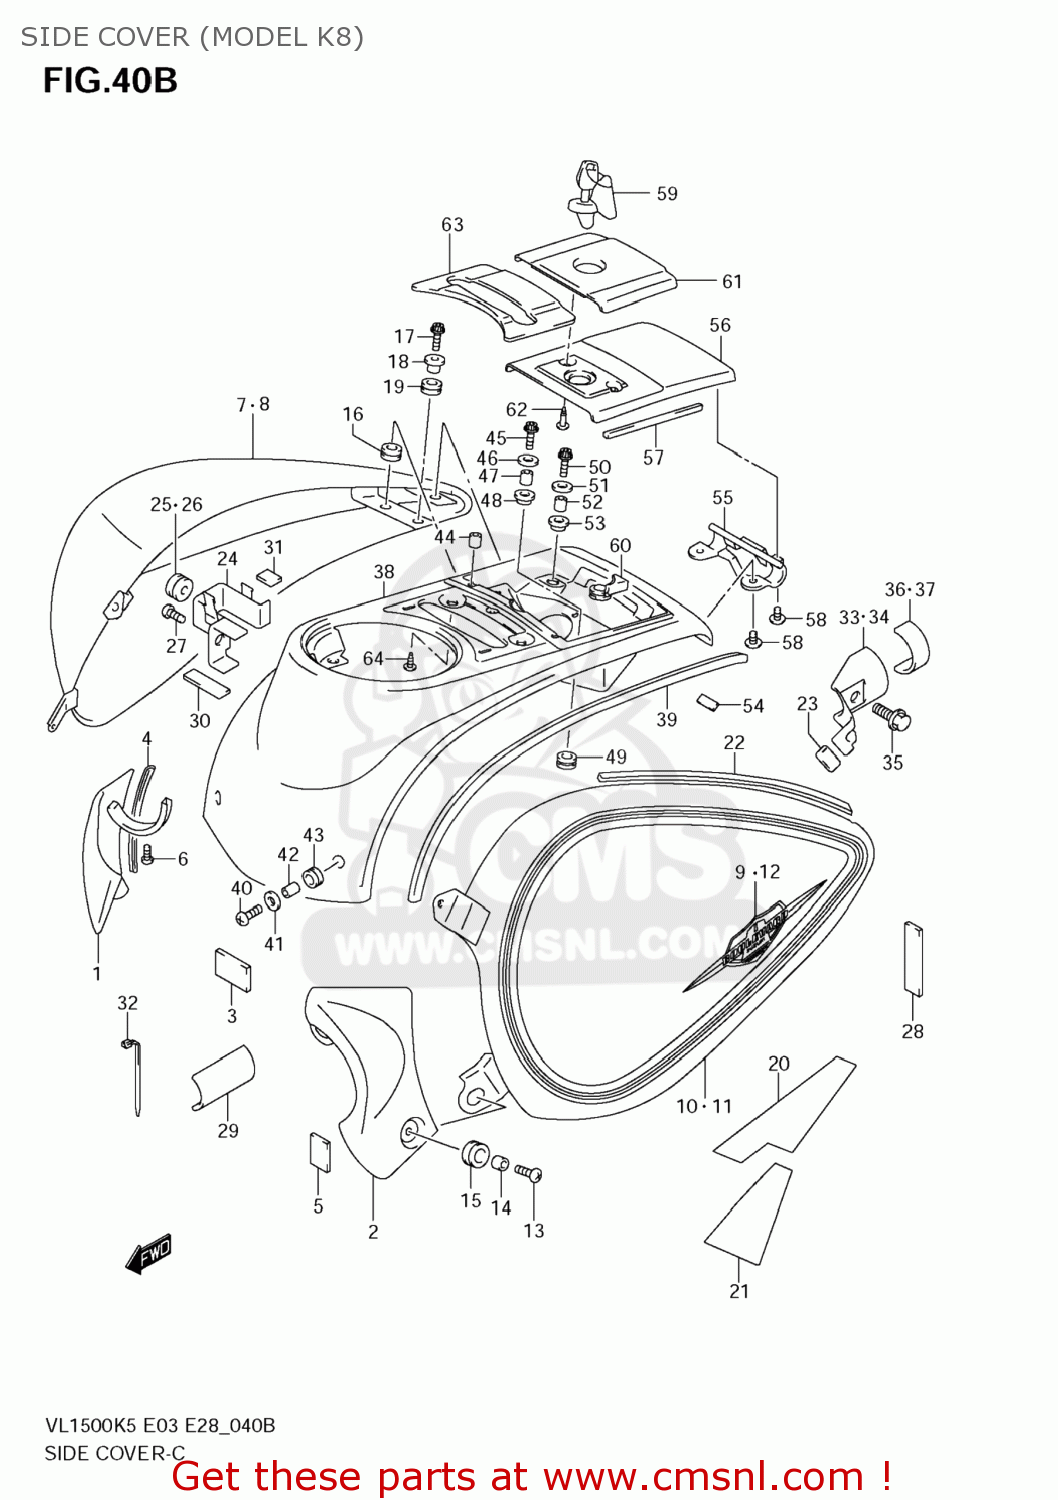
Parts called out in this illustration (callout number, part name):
1	COVER,FRAME HEAD,R
2	COVER,FRAME HEAD,L
3	CUSHION,METER COVER RE
4	MOLDING,FRAME HEAD COVER
5	PROTECTOR,FRAME COVER
6	SCREW(6X20)
7	COVER ASSY,SIDE UPR,R
8	COVER ASSY,SIDE UPR,R
9	EMBLEM,SIDE CO
10	COVER ASSY,SIDE UPR,L
11	COVER ASSY,SIDE UPR,L
12	EMBLEM,SIDE CO
13	SCREW(6X16)
14	SPACER(6.5X9X7.2)
15	CUSHION
16	CUSHION,SIDE UP METER & FRAME
17	BOLT
18	WASHER,SIDE UPR COVER
19	CUSHION,SIDE UPR COVER
20	SHIELD,SIDE UPR COVER,R
21	SHIELD,SIDE UPR COVER,L
22	MOLDING,SIDE UPR COVER UNDER
23	CUSHION,BRACKET
24	BRACKET,SIDE UPR COVER
25	CUSHION
26	CUSHION
27	BOLT
28	TAPE,HEAT SHIELD
29	CUSHION,SIDE COVER FR
30	PROTECTOR,STARTING MOTOR LEAD
31	PROTECTOR,CTR
32	CLAMP(L:165)
33	BRACKET,SIDE UPR COVER,R
34	BRACKET,SIDE UPR COVER,L
35	BOLT
36	CUSHION,BRACKET NO.1
37	CUSHION,BRACKET NO.2
38	COVER,METER & FUEL INLET
39	MOLDING,METER COVER
40	SCREW(6X16)
41	WASHER(6.5X18X1.5)
42	SPACER(6.5X9X5.7)
43	CUSHION
44	CUSHION
45	BOLT
46	WASHER(6.5X18X1.6)
47	SPACER(6.5X9X11)
48	CUSHION,METER COVER
49	CUSHION,SIDE UP METER & FRAME
50	BOLT
51	WASHER(6.5X18X1.6)
52	SPACER(6.5X9X5.7)
53	CUSHION
54	CUSHION,METER COVER RE
55	HINGE,FUEL LID
56	LID,FUEL INLET
57	CUSHION,FUEL LID
58	SCREW
59	LOCK SET,COVER
60	CUSHION,RR,L
61	COVER,FUEL LID
62	SCREW
63	COVER,METER SWITCH
64	SCREW
